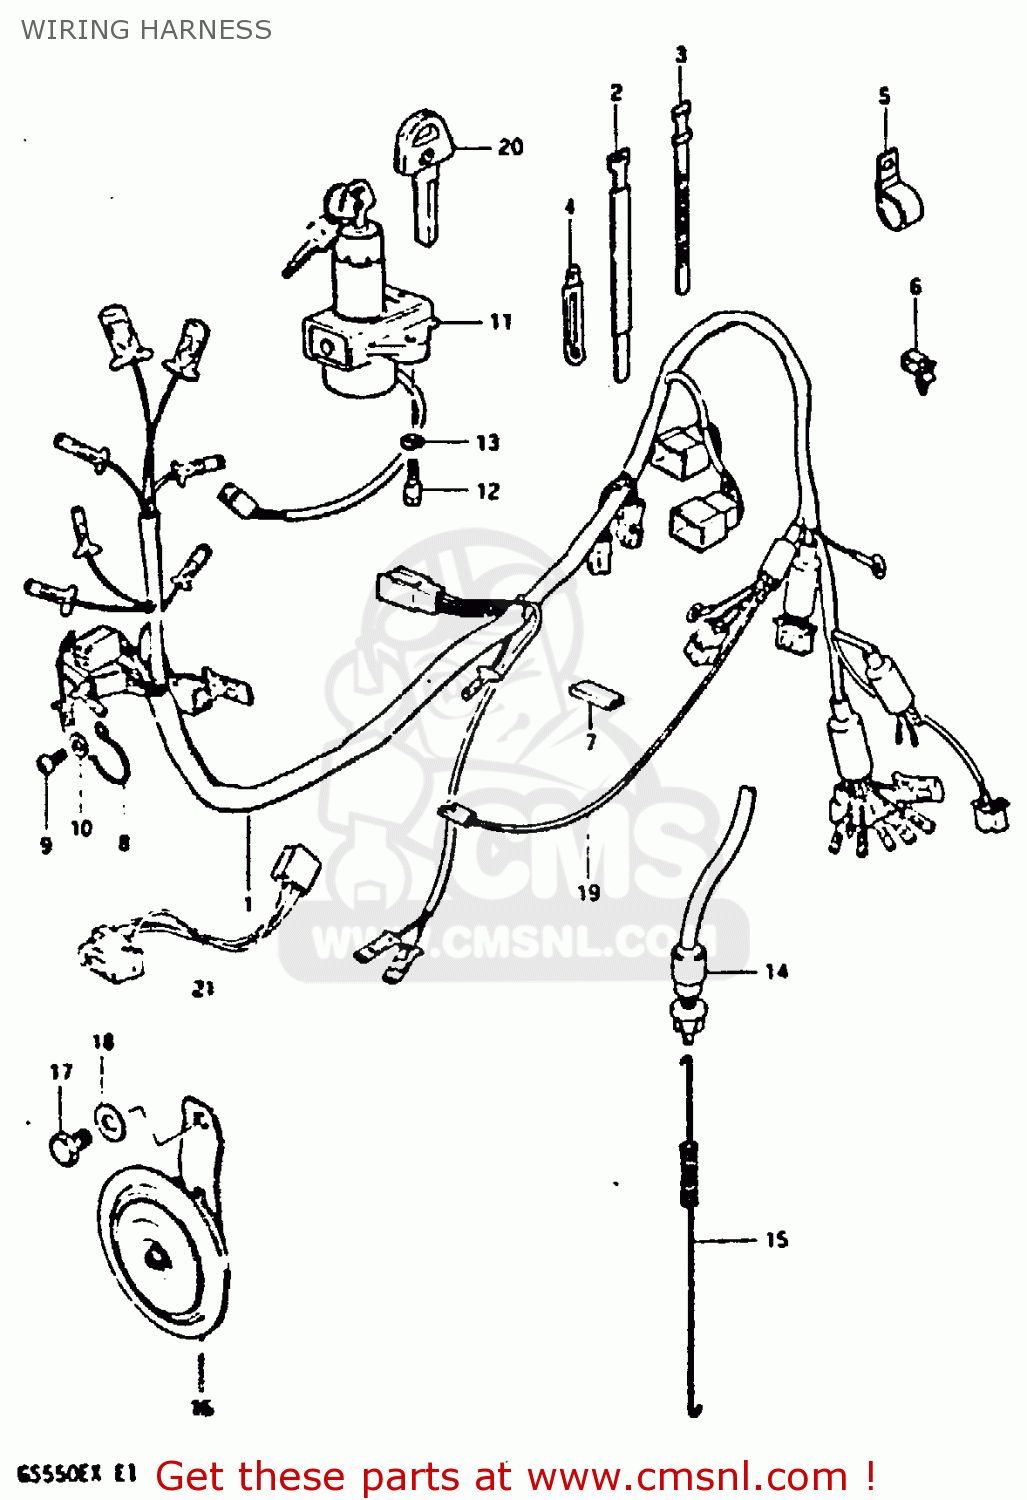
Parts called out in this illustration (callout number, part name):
1	WIRING HARNESS
2	CLAMP
3	CLAMP(L:120)
4	CLAMP
5	CLAMP
6	CLIP
7	PROTECTOR,WIRING HARNESS
8	GUIDE,WIRING HARNESS
9	SCREW 6X12
10	WASHER
11	LOCK ASSEMBLY,STEERING
12	BOLT
13	LOCK WASHER
14	SWITCH ASSEMBLY,STOP LAMP
15	SPRING
16	HORN ASSEMBLY
17	BOLT 8X12
18	WASHER
19	WIRE
20	KEY,BLANK
21	LEAD WIRE,HEADLAMP
